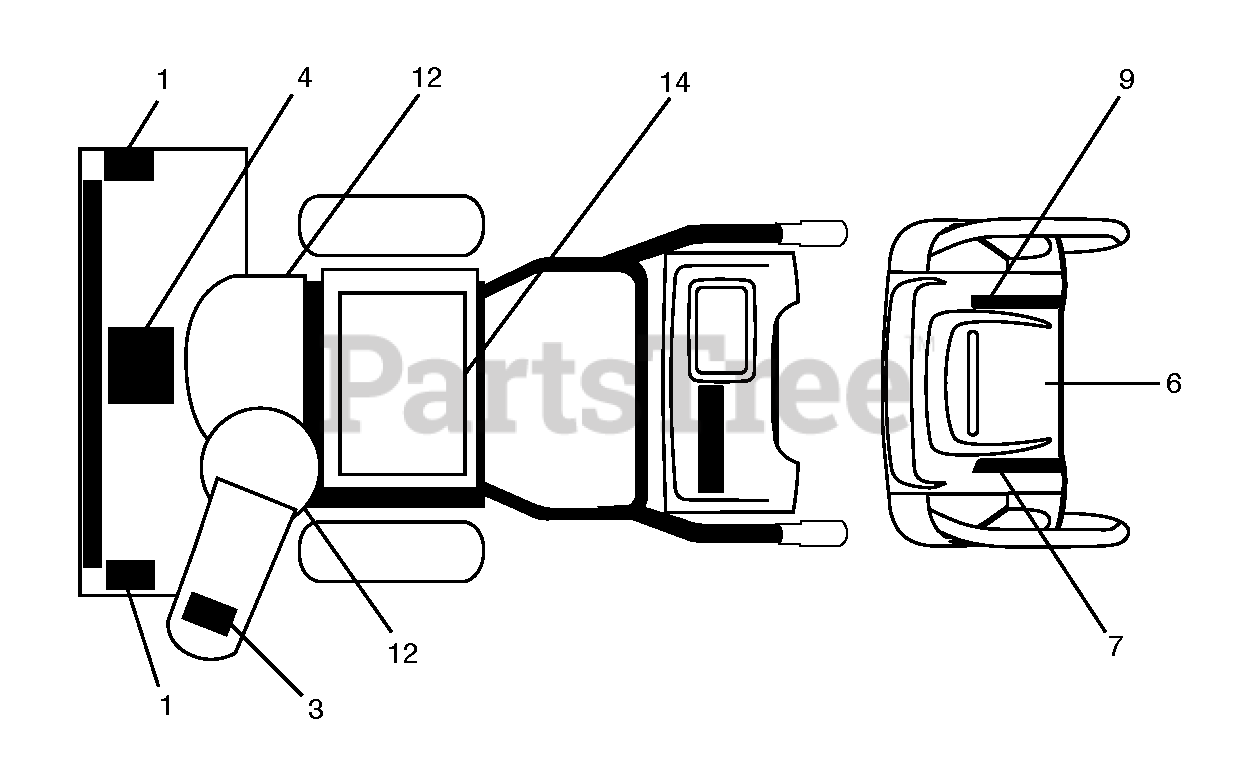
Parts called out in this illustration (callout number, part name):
1	DECAL.AUGER.SAFETY.
3	DECAL.CHUTE.SAFETY.
4	DECAL.AUGER."
7	DECAL.CONS.LT.WO/DEFL.GRY
9	DECAL.CONS.RT.SPD/LEV/PWRST.
12	DECAL.BELT.GUARD.
14	DECAL.FENDER
